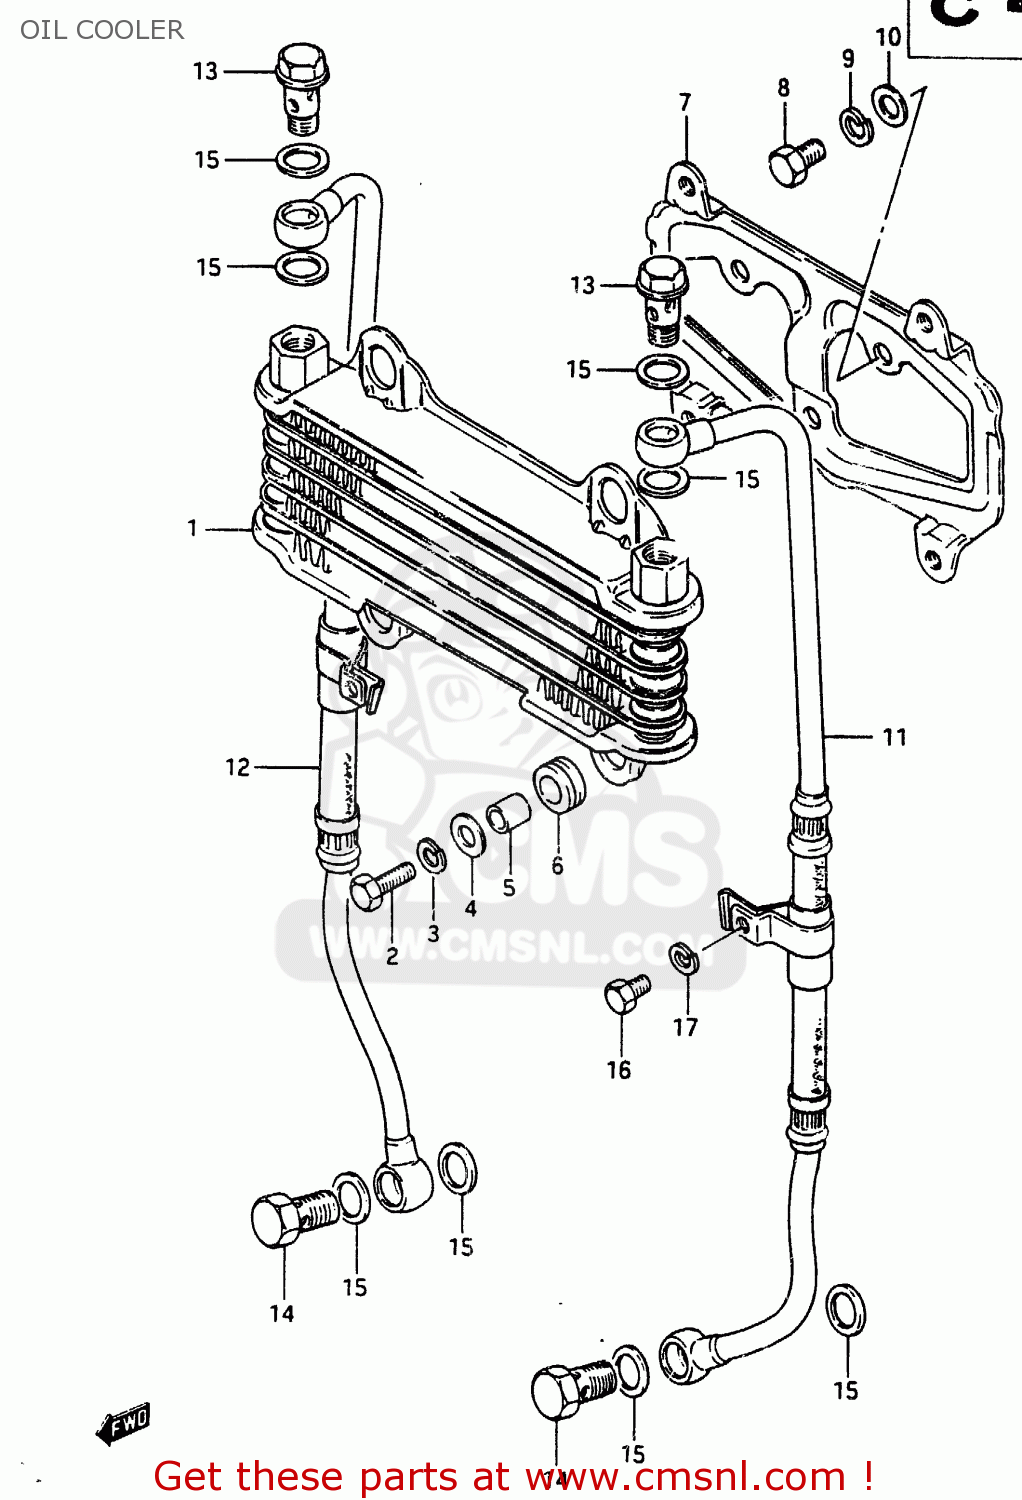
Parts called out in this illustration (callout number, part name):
1	COOLER ASSEMBLY,ENGINE OIL
2	BOLT
3	WASHER,LOCK
4	WASHER (6.5X18X1.6)
5	SPACER (6.8X10X10)
6	CUSHION
7	BRACKET,OIL COOLER
8	BOLT
9	WASHER,LOCK,8.
10	WASHER
11	HOSE,ENGINE OIL,LEFT
12	HOSE,ENGINE OIL,RIGHT
13	BOLT UNION
14	BOLT UNION
15	GASKET(14X20X1.5) (NAS)
16	BOLT
17	WASHER,LOCK
